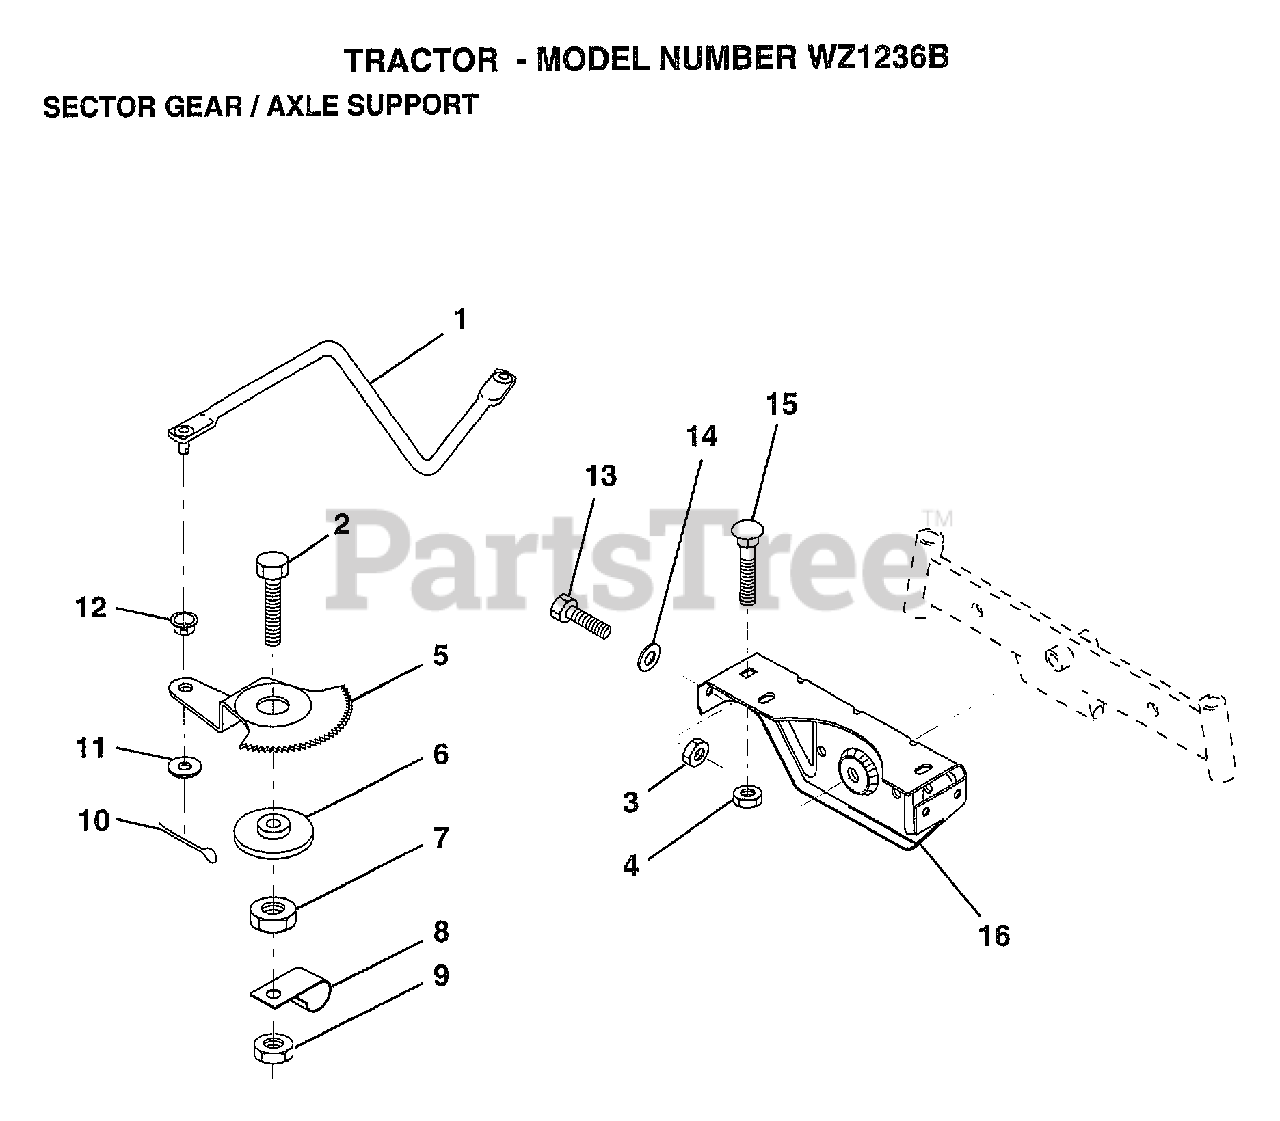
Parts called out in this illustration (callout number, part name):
1	DRAG LINK
2	"BOLT,HEX"
5	GEAR SECTOR
6	BUSHING
7	NUT
8	CLIP INSULATOR
9	NUT LTV
10	COTTER PIN
11	WASHER
12	BUSHING.DRAGLINK
13	BOLT
14	WASHER
15	BOLT
16	SUPT AXLE FRONT
